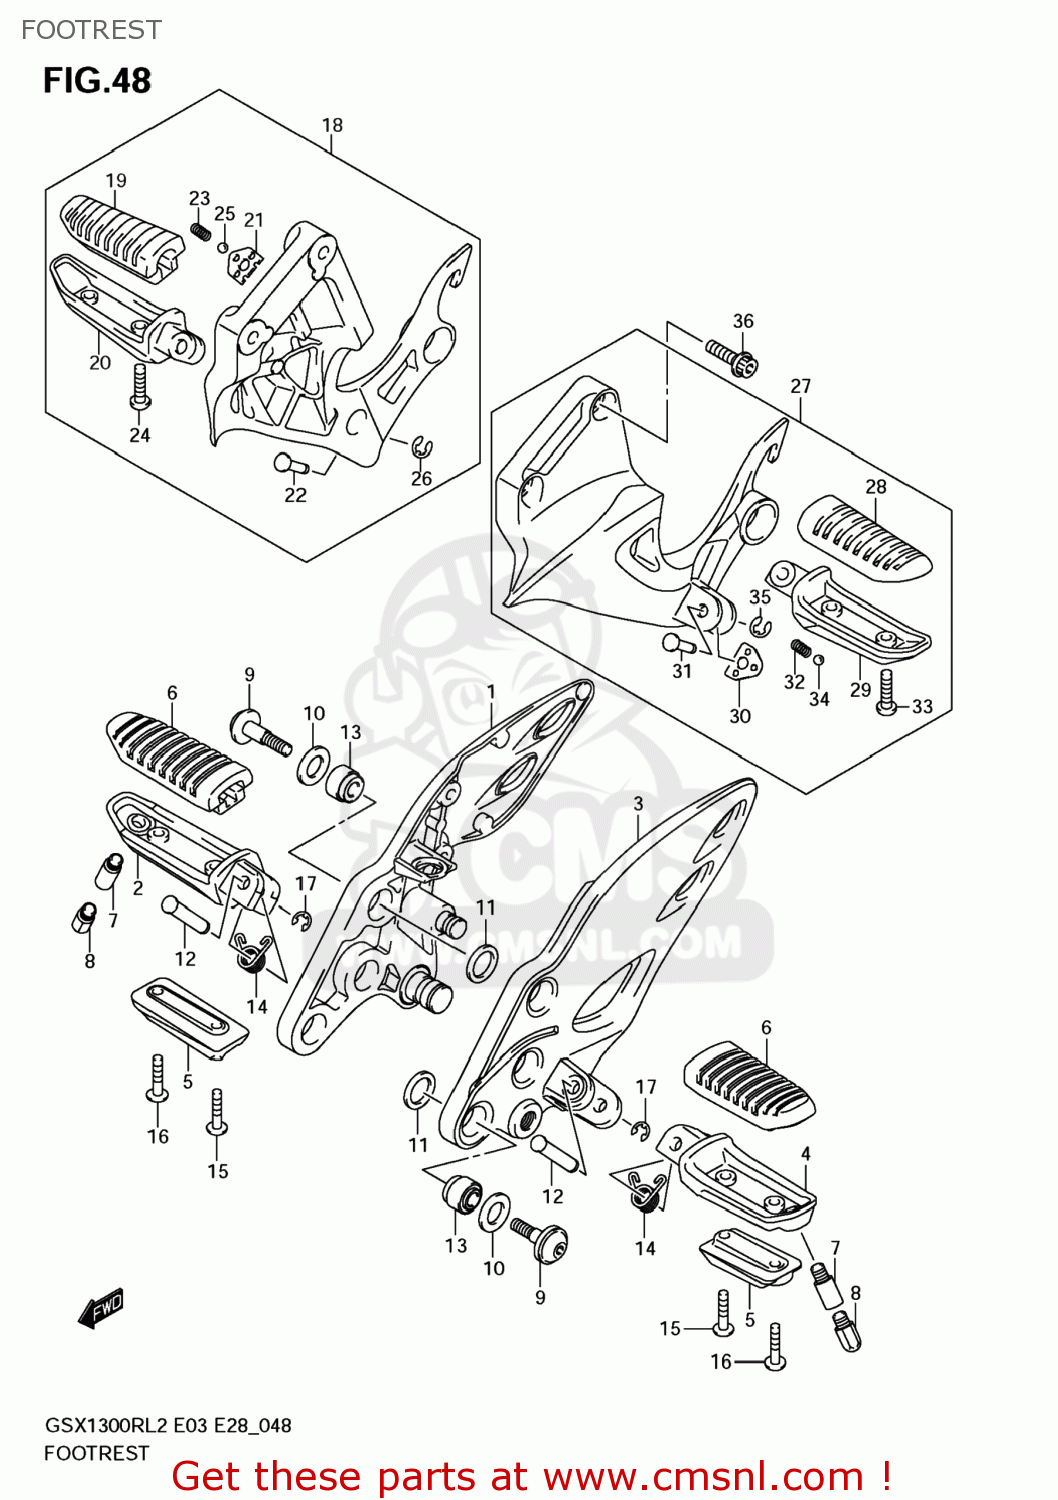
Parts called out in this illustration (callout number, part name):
1	BRACKET,FR FOOTREST,R
2	BAR,FR FOOTREST,R
3	BRACKET,FR FOOTREST,L
4	BAR,FR FOOTREST,L
5	BALANCER,FR FOOTREST
6	RUBBER,FOOTREST BAR
7	SENSOR,FOOTREST
8	SENSOR,FOOTREST
9	BOLT(8X30)
10	WASHER(13.7X24X2)
11	WASHER(17.2X24X2.2)
12	PIN
13	BUSH(8.4X20X16)
14	SPRING
15	SCREW
16	SCREW
17	E RING
18	FOOTREST ASSY,PILLION,R
19	RUBBER,FOOTREST
20	BAR,PILLION FOOTREST,R
21	PLATE,PILLION FOOTREST
22	PIN
23	SPRING
24	SCREW
25	BALL
26	E RING
27	FOOTREST ASSY,PILLION,L
28	RUBBER,FOOTREST
29	BAR,PILLION FOOTREST,L
30	PLATE,PILLION FOOTREST
31	PIN
32	SPRING
33	SCREW
34	BALL
35	E RING
36	BOLT(8X30)
